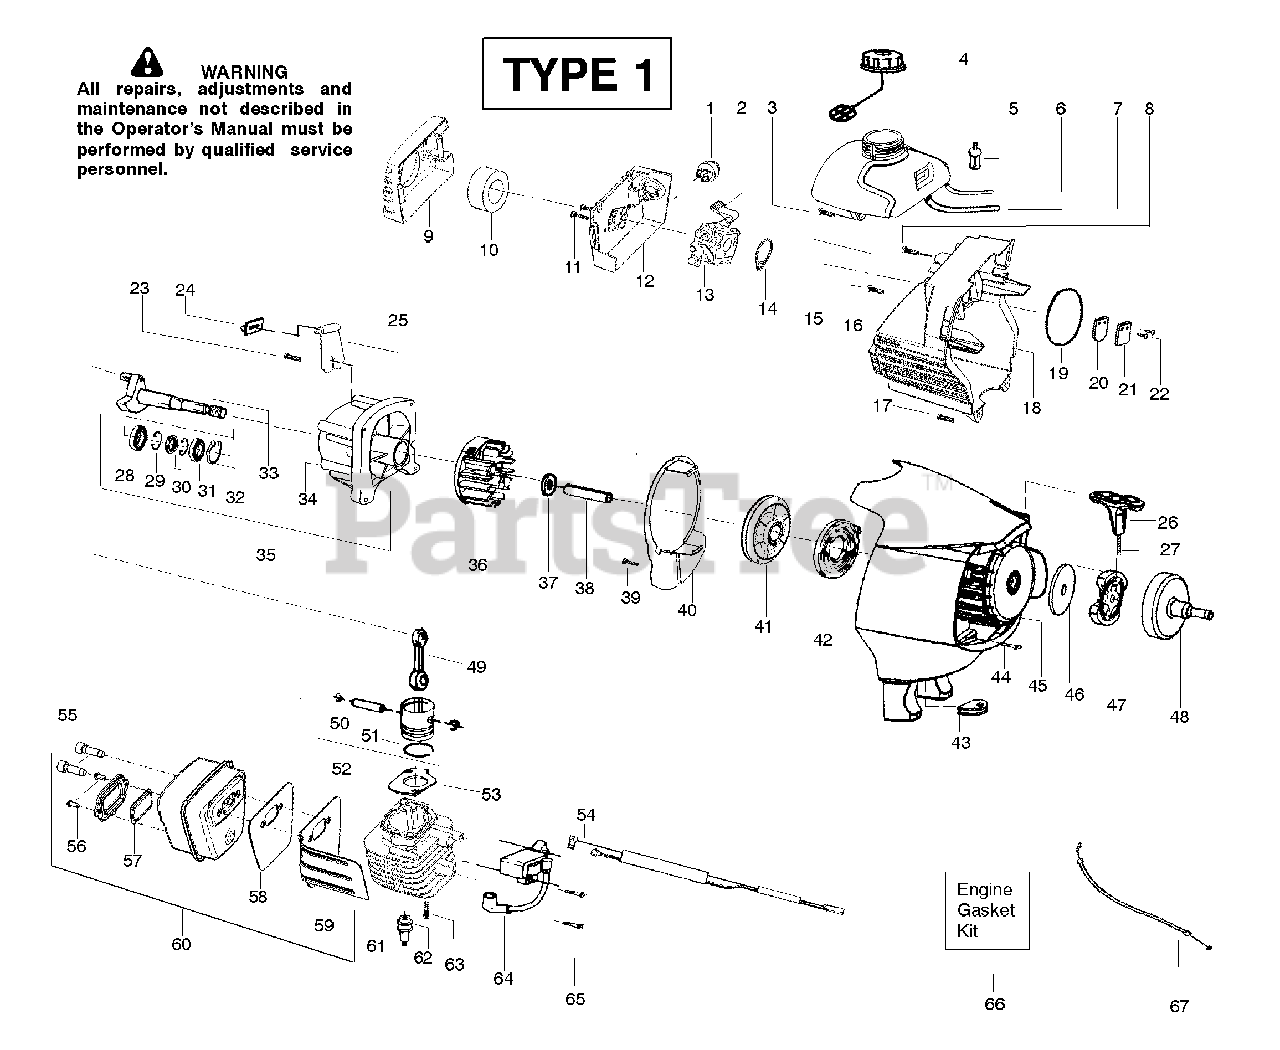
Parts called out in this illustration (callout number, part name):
1	Bulb-Purge
2	Kit-Choke Lever
3	Screw-tank
4	Cap-Fuel w/ret.
5	Assy-Fuel pickup
6	Kit-Fuel line
7	Kit-Fuel/Purge line
9	Cover-Air box
10	Filter-Air
11	Screw-Carb.
13	Kit-Carb assy.
14	Seal-Carb.
15	Assy-Fuel Tank
16	Screw-Crankcase
17	Screw-Shroud
18	Assy-Rear Shroud
19	O-ring-Shroud
20	Valve-Reed
21	Stop-Reed
22	Screw-Reed stop
23	Screw-Retainer
24	Isolator-Tank
25	Ret.-Tank
26	Handle-Starter
27	Kit-Rope
28	Bearing-Inner
29	Retainer
31	Bearing-Outer
32	Ret.-Crankshaft
33	Assy-Crankshaft
34	Assy-Crankcase
35	Assy-C'case/C'shaft
36	Assy-Flywheel
39	Screw-Baffle
40	Plate-Baffle
41	Kit-Pulley
42	Spring-Starter
44	Screw-F/hsg.
45	Assy-Fan Housing
46	Washer-Clutch
47	Assy-Clutch
48	Assy-Drum/Adapter
49	Assy-Conn. Rod
50	Ret.-Piston pin
51	Ring-Piston
52	Kit-Piston
53	Gasket-Cylinder
54	Assy-Leadwire
55	Bolt-Muffler 1/4"-20
57	Kit-Spark Arrestor
58	Gasket-Muffler
60	Kit-Muffler
61	Cylinder
62	Plug-Spark
63	Bolt-Cyl. 1/4"-20
64	Module-Ignition
65	Screw-Module
66	Kit-Gasket/Seal
67	Assy-Throttle cable
